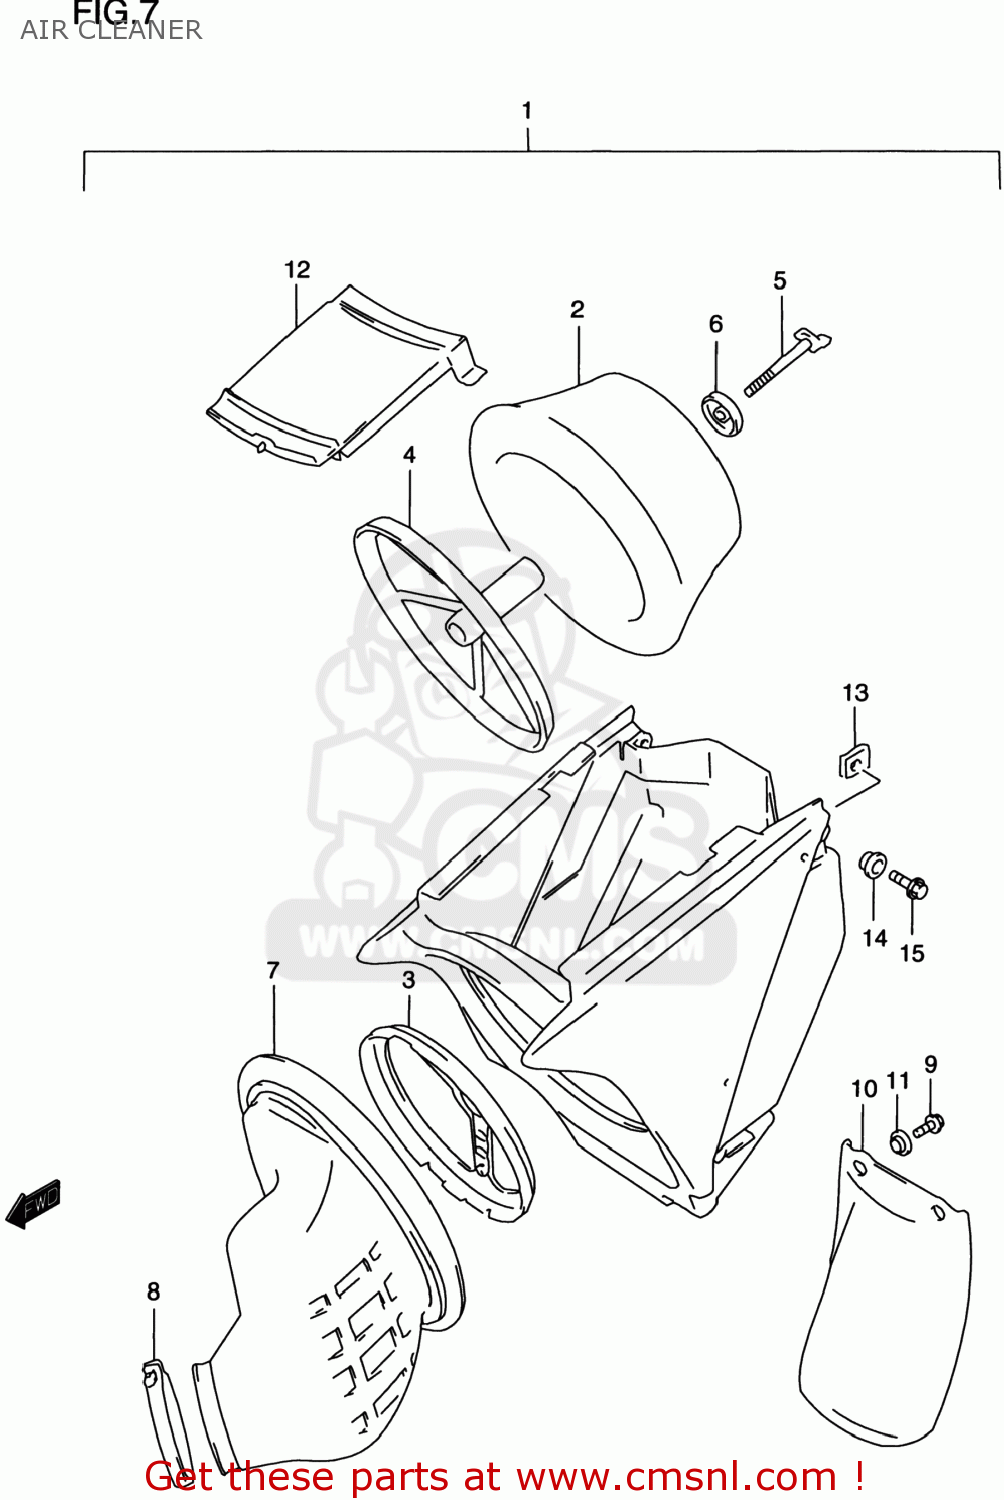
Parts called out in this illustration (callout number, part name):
1	CLEANER ASSEMBLY,AIR
2	FILTER ASSY
3	BASE,FILTER
4	HOLDER,FILTER
5	BOLT,WING
6	WASHER,AIR CLEANER
7	TUBE,OUTLET
8	CLAMP
9	BOLT
10	MUDGUARD
11	COLLAR
12	CAP,AIR CLEANER
13	HOLDER,REAR BU
14	WASHER
15	SCREW
